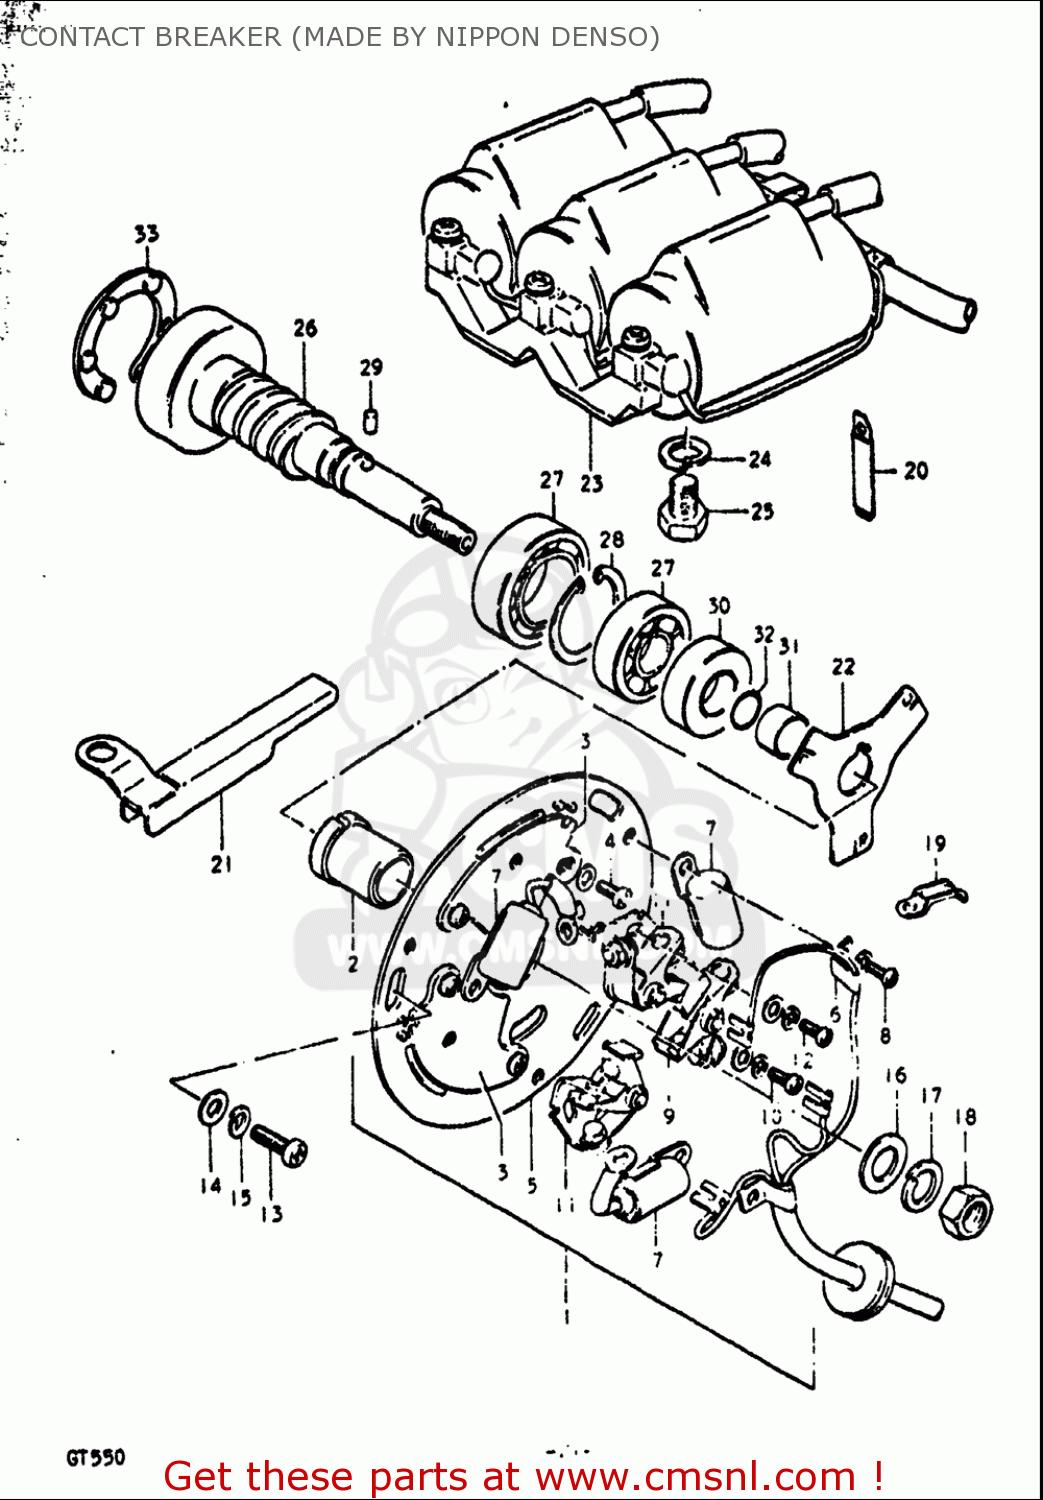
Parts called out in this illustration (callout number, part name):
4	SCREW 4X6
7	CONDENSER
8	SCREW
9	POINT ASSY
10	SCREW 4X6
11	POINT ASSY
12	SCREW 4X6
13	SCREW(5X12)
14	WASHER
15	WASHER,LOCK
16	WASHER
17	WASHER,LOCK
18	NUT
19	CLAMP
24	WASHER,LOCK
25	BOLT
27	BEARING
28	CIRCLIP
29	PIN
30	SEAL,OIL(20X35X7)
32	O RING(D:1.3,ID:11.6)
